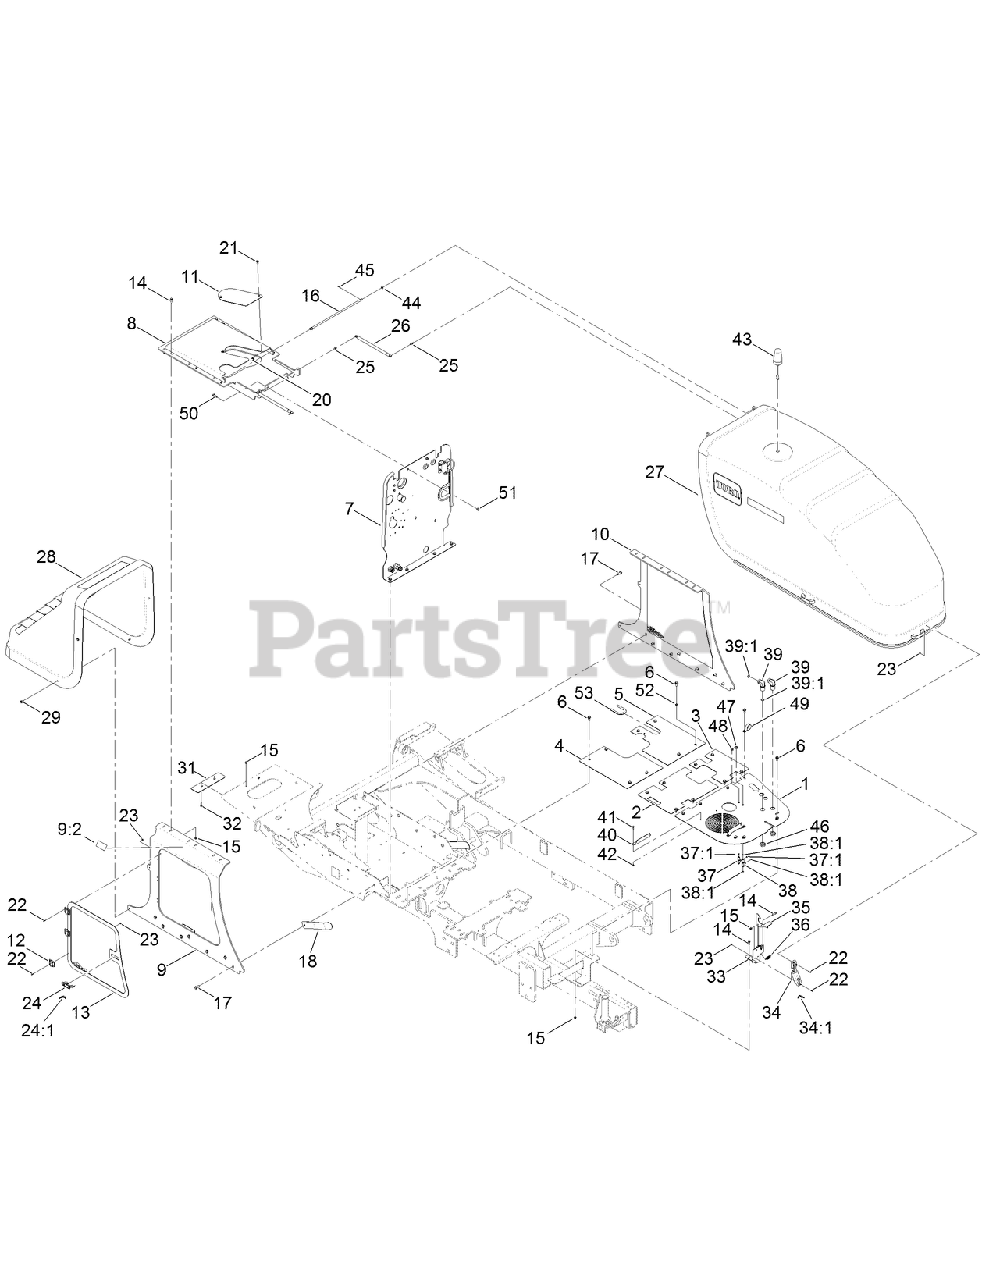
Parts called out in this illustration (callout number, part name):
1	PLATE-BULKHEAD
2	PLATE-SEAL, HOOD
3	PLATE-SEAL, HOOD
4	PLATE-HOOD SEAL
5	PLATE-HOOD SEAL
6	SCREW-HHF
7	BULKHEAD ASM
8	MOUNTING-HOOD
9	HOOD MOUNTING ASM
9:2	DECAL-WARNING, HOT SURFACE
10	MOUNT-HOOD
11	PLATE-COVER
13	DOOR-SIDE
14	SCREW-HHF
15	NUT-LOCK, HHF
16	PIN-MOUNT, HOOD
17	SCREW-HHF
18	GUIDE-HOOD
21	SCREW-HHF
22	SCREW-PRH
23	NUT-KEPS
24	LATCH-TRIGGER, RAISED (W/LOCK)
24:1	KEY-REPLACEMENT
25	STUD-BALL
26	SPRING-GAS
27	FRONT HOOD ASM
28	REAR HOOD ASM
29	SCREW-HHF
31	PLATE-SANDWICH, HOOD STOP
32	SCREW-HHF
33	MOUNT-HOOD, SAFETY LATCH
34	LATCH-DRAW, LOCKABLE
34:1	KEY-REPLACEMENT
35	HOOK-HOOD, SAFETY LATCH
36	SPRING-TENSION
37	FITTING-TEE
37:1	O-RING
38	FITTING-TEE, BULKHEAD
38:1	O-RING
39	FITTING-ELBOW, 90
39:1	O-RING
40	PLATE-MOUNT, FAN
41	SCREW-HHF
42	NUT-FLANGE, NI
43	LIGHT-STROBE
44	WASHER-THRUST
45	PIN-COTTER
46	NUT-BULKHEAD
47	NUT-LOCK
48	NUT-LOCK
49	CLAMP-R
50	SCREW-HHF
51	NUT-LOCK, NI
52	WASHER-LOCK, EXT
53	TRIM-TANK
